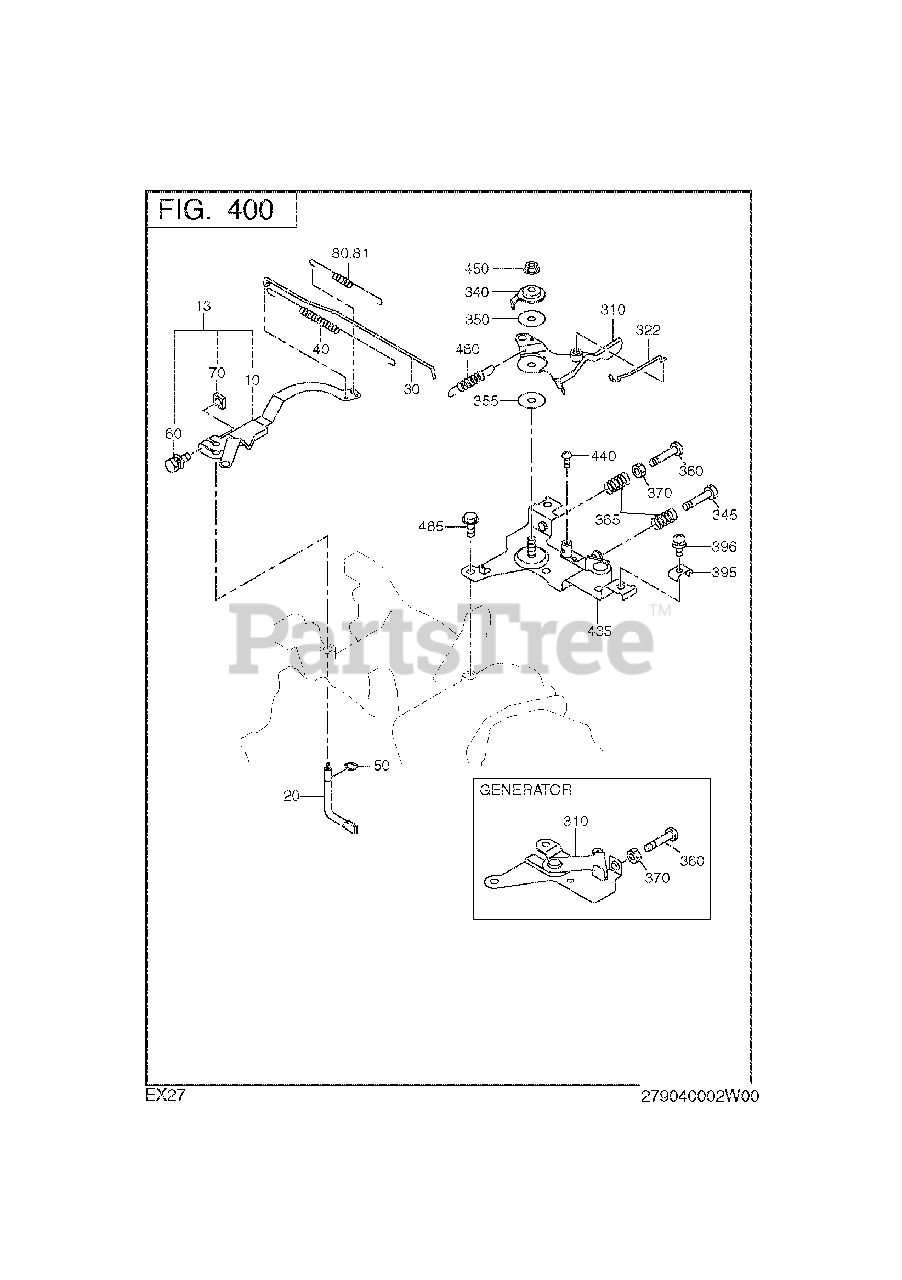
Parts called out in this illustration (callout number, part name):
10	GOVERNOR LEVER
20	GOVERNOR SHAFT
30	GOVERNOR ROD CP
60	BOLT AND WASHER AY
80	GOVERNOR SPRING
310	SPEED CONT.LEVER CP
355	FRICTION WASHER
365	SPRING (ADJUST)
396	SCREW AND WASHER AY
435	SPEED CONTROL BRKT. CP
